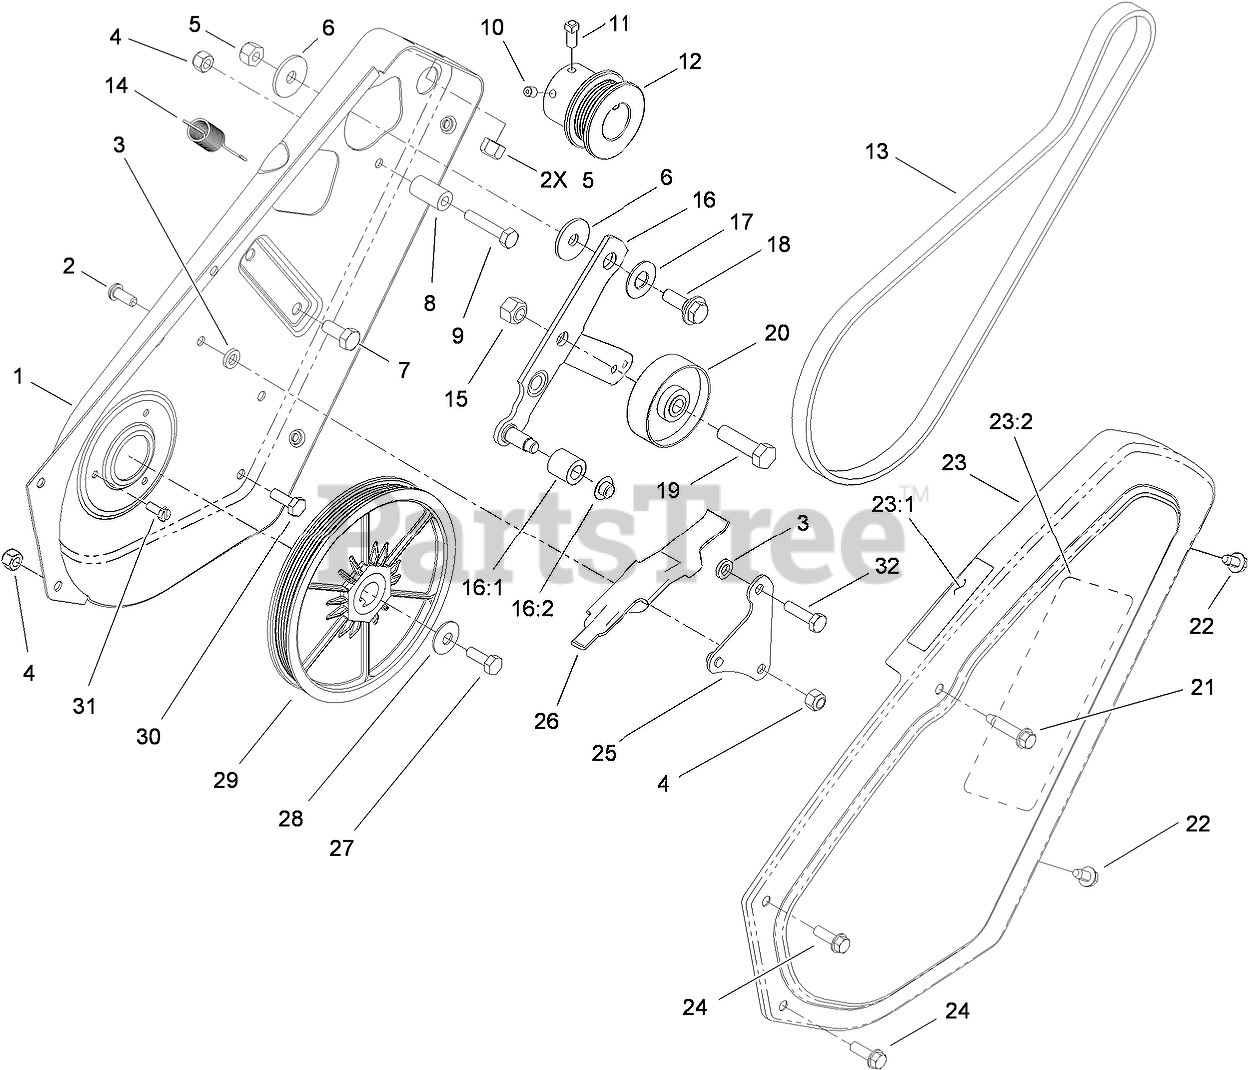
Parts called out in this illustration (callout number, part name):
1	PLATE-SIDE, LH
2	SCREW-HSBH
3	SPACER-PLATE, PIVOT
4	NUT-LOCK, NI
5	NUT-LOCK, NI
6	WASHER-PIVOT
7	SCREW-HH
8	SLEEVE-GUIDE, BELT
9	SCREW-HH
10	SCREW-HSH
11	SCREW-SQH
12	PULLEY-ENGINE
13	BELT-DRIVE
14	SPRING-EXTENSION
15	NUT-LOCK, CONE
16	IDLER ARM ASM
16:1	ROLLER-BRAKE
16:2	NUT-PUSH
17	WASHER
18	SCREW-SHOULDER
19	SCREW-HH
20	PULLEY-IDLER
21	SCREW-HWH
22	SCREW
23	COVER-DRIVE
23:1	DECAL-WARNING
23:2	DECAL
24	SCREW-HWH
25	PIVOT PLATE ASM
26	BRAKE-ARM
27	SCREW-HH
28	WASHER-BELLEVILLE
29	PULLEY ROTOR ASM
30	SCREW-HH
31	SCREW-SHH
32	SCREW-HH
